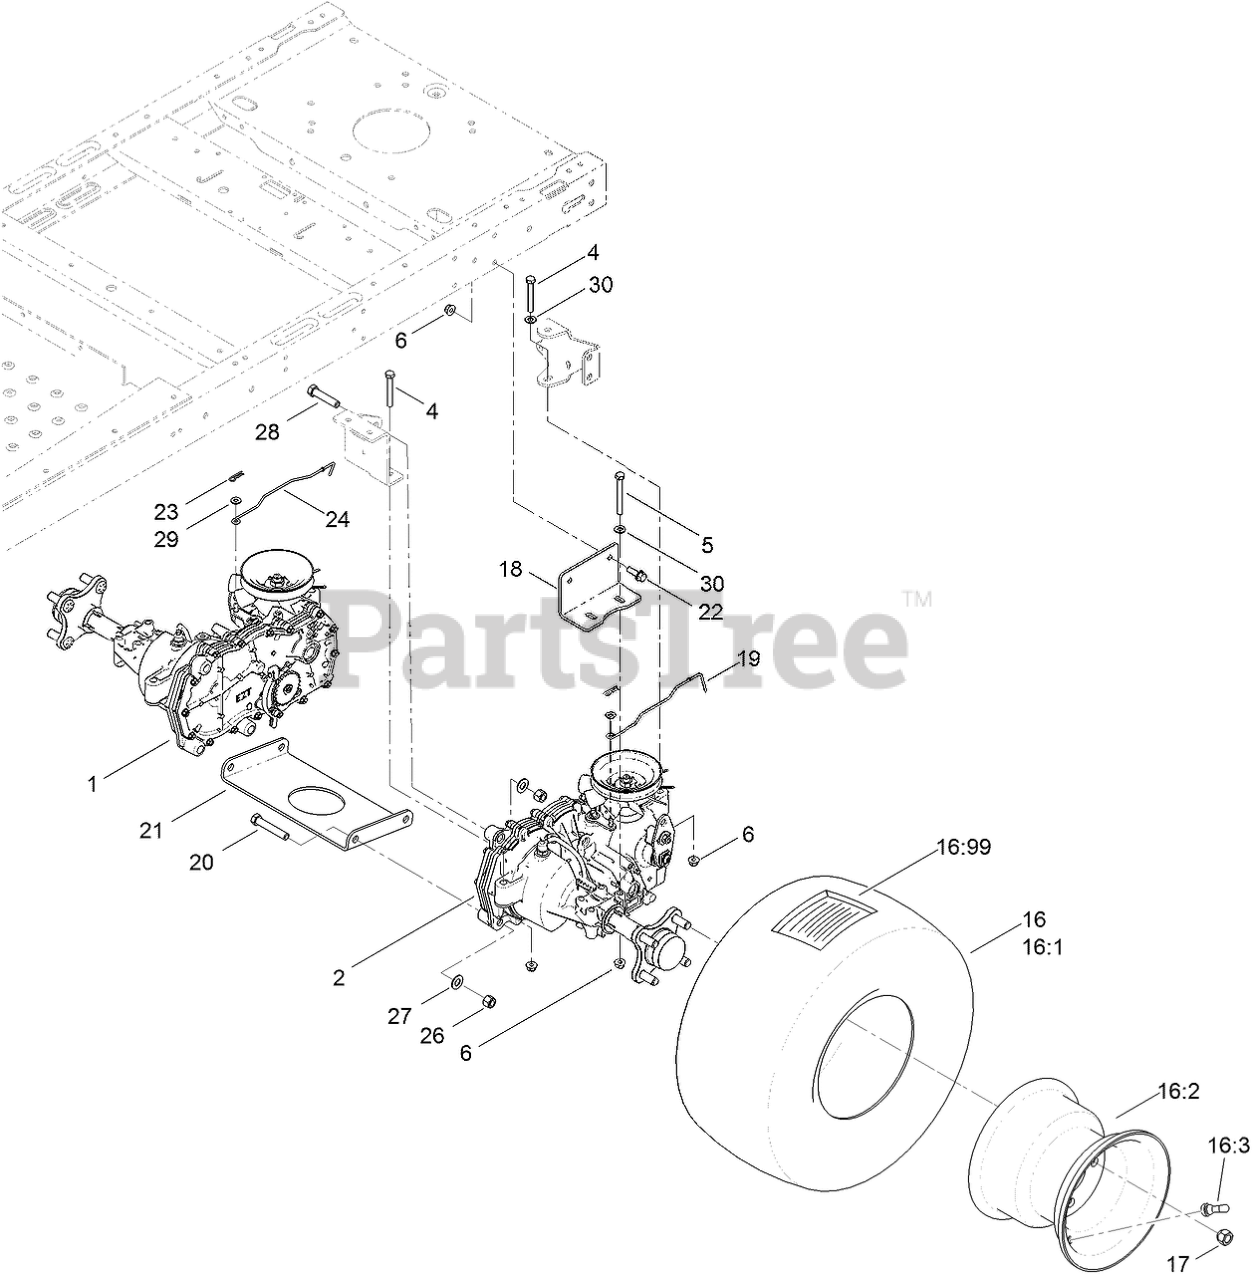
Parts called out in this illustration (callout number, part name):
1	RH HYDRO TRANSAXLE ASM
2	LH HYDRO TRANSAXLE ASM
4	SCREW-HH
5	SCREW-HH
6	NUT-HF, NI
16	4 PLY WHEEL AND TIRE ASM
16:1	TIRE-4 PLY
16:3	STEM-VALVE
16:99	TUBE-TIRE
17	NUT-LUG
18	MOUNT-HYDRO
19	ROD-BYPASS, LH
20	SCREW-HH
21	PLATE-CROSS, HYDRO
22	SCREW-HHF
23	PIN-COTTER
24	ROD-BYPASS, RH
26	NUT-LOCK, NI
27	WASHER-FLAT
28	SCREW-HH
29	WASHER
30	WASHER-PLAIN
